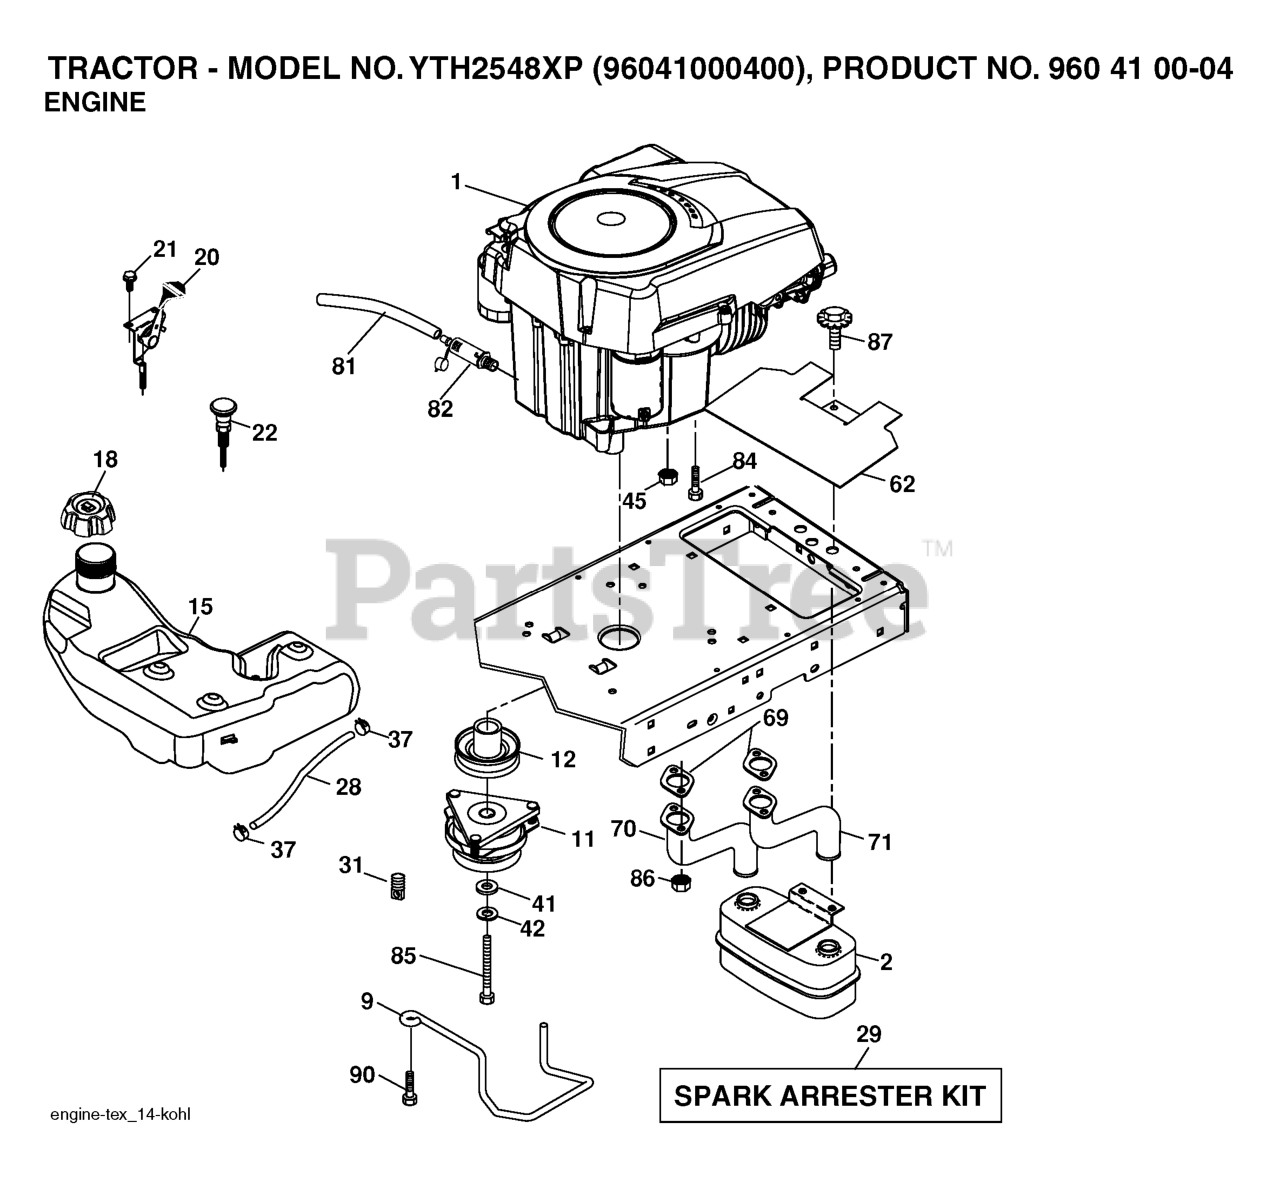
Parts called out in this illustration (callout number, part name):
2	MUFFLER.TWIN.CYL.LOW.TONE
9	KEEPER.BELT.ENGINE.3.25 (3 2)
11	CLUTCH MZ ZTR GT.48/54"1.125"
12	PULLEY.ASM.ENGINE.1-1/8X3-1/4
15	TANK.FUEL.4GAL
18	CAP.FUEL.TANK.3"GREY
20	THROTTLE CONTROL
21	SCREW
22	CONTROL.CHOKE.ERGO.PUSH-IN.BLA
28	REPL BY 532 00 85-43
29	KIT.SPARK ARRESTOR 794945 B&S
37	HOSE CLAMP
42	LOCKWASHER
45	NUT
62	RP SHIELD HEAT MUFFLER
70	RP.PIPE-EXHAUST LH
71	RP.PIPE-EXHAUST RH
81	TUBE, DRAIN OIL ASM.
82	PLUG DRAIN OIL EASY
84	SCREW.3/8-16
85	BOLT HEX 7/16-20 X 3.75 GR. 5
86	NUT.HEX.FLANGE.TOPLOCK
87	BOLT.5/16-18UNCX1.W/SEMS.BLK
90	SCREW 3/8-16X1
91	BUSHING.1.375OD
